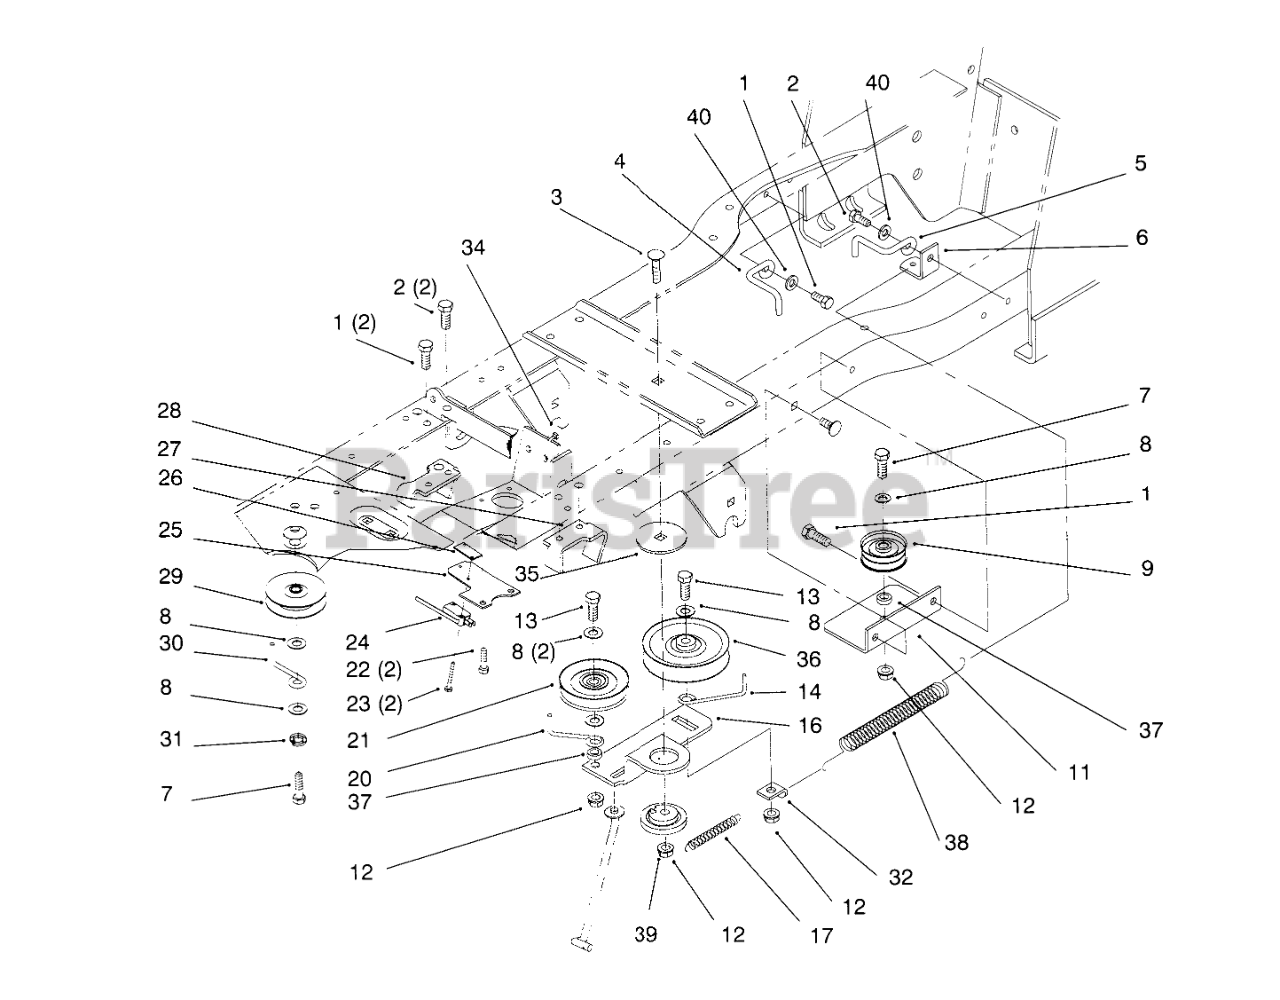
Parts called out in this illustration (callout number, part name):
1	Screw-HH (Only On: 72042,72062)
2	Screw-TAP (Only On: 72042,72062)
3	Screw-CARR (Only On: 72042,72062)
4	Guide-Belt RH (Only On: 72042,72062)
5	Guide-Belt LH (Only On: 72042,72062)
6	Bracket-Idler Spring (Only On: 72042,72062)
7	Screw-HH (Only On: 72042,72062)
8	Washer-Flat (Only On: 72042,72062)
9	Pulley-Idler (Only On: 72042,72062)
11	Bracket-Idler Rear (Only On: 72042,72062)
12	Nut-Lock (Only On: 72042,72062)
13	Screw-HH (Only On: 72042,72062)
14	Guide-Belt (Only On: 72042,72062)
16	Arm-Idler (Only On: 72042,72062)
17	Spring-Extension (Only On: 72042,72062)
20	Guide-Belt (Only On: 72042,72062)
21	Pulley-Idler (Only On: 72042,72062)
22	Screw-TAP (Only On: 72042,72062)
23	Screw (Only On: 72042,72062)
24	Switch-Micro (Only On: 72042,72062)
25	Bracket-Micro Switch (Only On: 72042,72062)
26	Nut-Speed (Only On: 72042,72062)
27	Bracket-Clutch (Only On: 72042,72062)
28	Bracket-Brake (Only On: 72042,72062)
29	Pulley-Idler (Only On: 72042,72062)
30	Guide-Belt (Only On: 72042,72062)
31	Washer-Lock (Only On: 72042,72062)
32	Clip-Spring (Only On: 72042,72062)
34	Tie Strap (Only On: 72042,72062)
35	Washer-Bearing (Only On: 72042,72062)
36	Pulley-Flat (Only On: 72042,72062)
37	Spacer (Only On: 72042,72062)
38	Spring-Extension (Only On: 72042,72062)
39	Bushing (Only On: 72042,72062)
40	Washer-Flat (Only On: 72042,72062)
